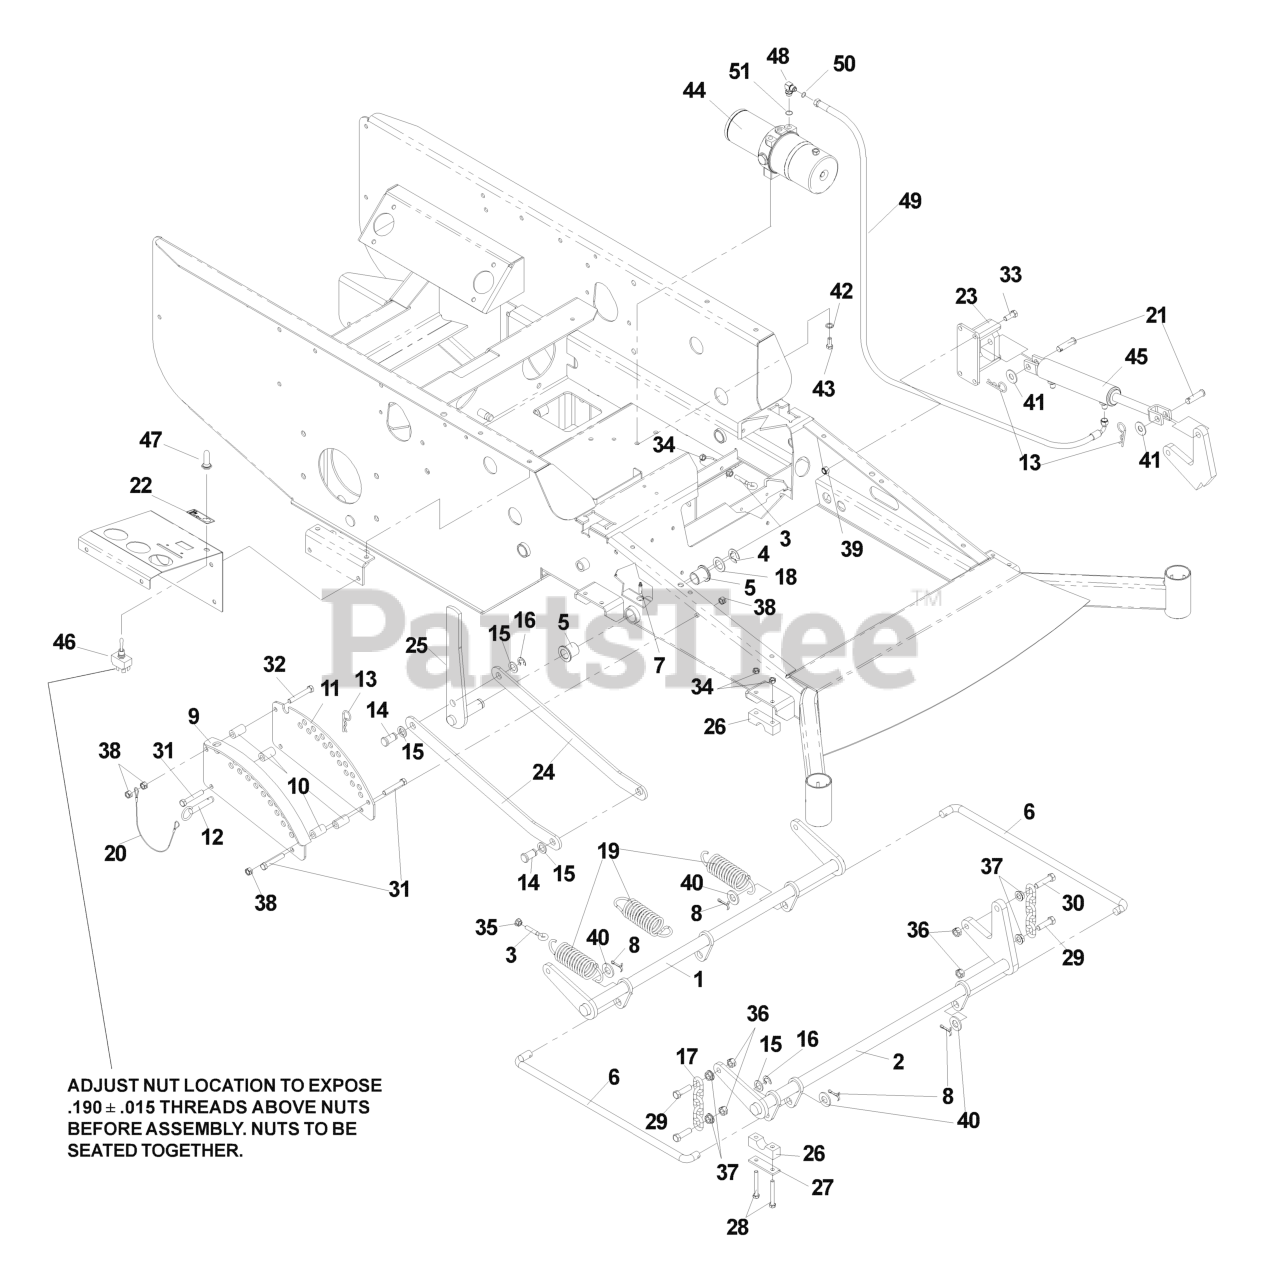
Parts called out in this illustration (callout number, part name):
1	SHAFT LIFT REAR
2	LIFT SHAFT WELDMT FRONT
3	EYEBOLT, RH
4	E-RING 7/8
5	BUSHING, FLANGED
6	CONNECTING LINK
7	GREASE ZERK LONG
8	COTTER PIN
9	ADJ. PLATE WLDMNT
10	DECK LIFT SPACER
11	ADJ. PLATE PAINTED
13	HAIRPIN #4
14	CLEVIS PIN
15	BUSHING
16	E-RING 5/8
17	LIFT CHAIN
18	BSHG .875 X 1.375 X .074 ZD
19	DECK LIFT SPRING
21	CLEVIS PIN 1/2 X 3/4
22	DECAL, LIFT SWITCH
23	CYLINDER MTG WLDMT
24	LIFT LINKAGE,PAINTED
25	LIFT LEVER
26	PILLOW BLOCK
27	REINFORCEMENT BAR
28	BOLT 5/16C X 2 1/2
29	HCS 7/16C X 1 1/2
30	HCS 7/16 - 14 X 1 3/4
31	HCS 3/8C X 2 1/4
32	HCS 3/8C X 2 1/2
33	HCS 3/8-16X1.GRD.5.ZD
34	NUT 5/16C CENTERLOCK
35	NUT 5/16C WHIZ
36	NUT 7/16C CENTERLOCK
37	NUT 7/16C WHIZ
38	NUT 3/8C CENTERBLOCK
39	NUT 3/8-16 NYLOC
40	WASHER 5/8 FLAT
41	WASHER 1/2 FLAT
42	SLW 3/8 STD
43	SCREW 3/8C X 3/4 HEX CAP
44	HYDRAULIC POWER UNIT
45	HYDRAULIC CYLINDER
47	SWITCH BOOT
